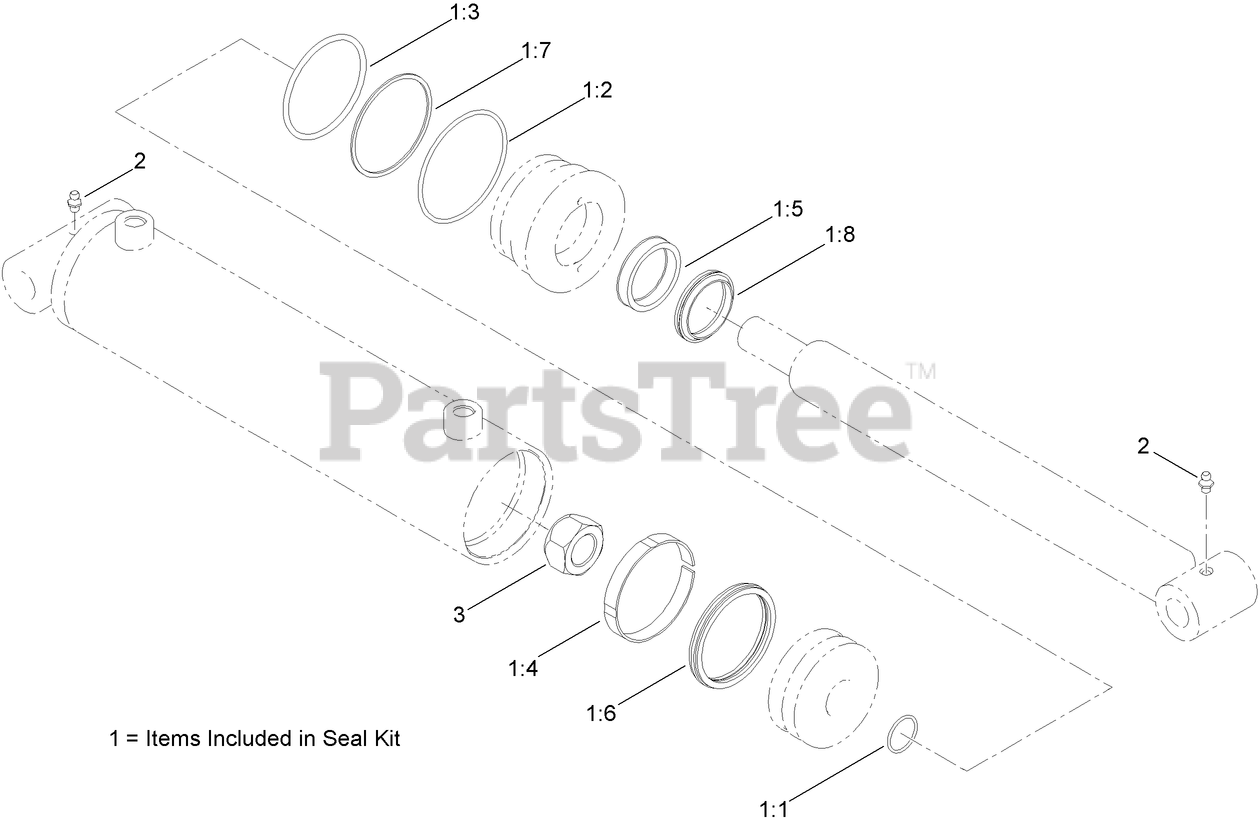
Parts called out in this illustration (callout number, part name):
1	SEAL KIT
1:1	O-RING
1:2	O-RING
1:3	O-RING
1:4	RING-PISTON BEARING
1:5	Seal-U Cup
1:6	SEAL-CROWN
1:7	Washer-Back Up
1:8	WIPER
2	FITTING-GREASE
3	NUT-LOCK, NI
